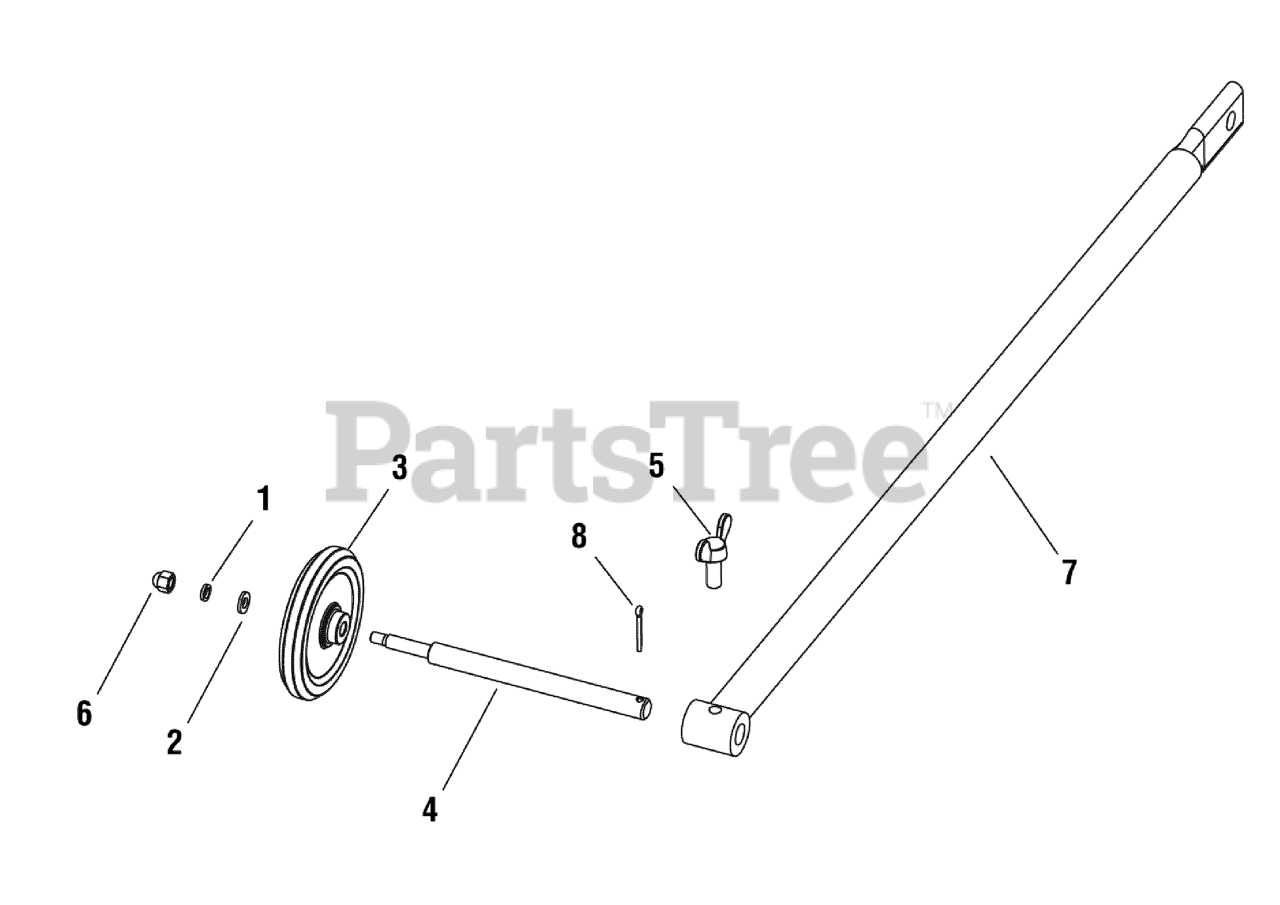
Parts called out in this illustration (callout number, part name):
1	WASHER, Spring
2	WASHER, Flat
3	GUIDE WHEEL
4	SHAFT, Guide Wheel
5	WINGNUT, M8 x 20
6	NUT, Acorn, M6
7	GUIDE ROD
8	SPLIT PIN
